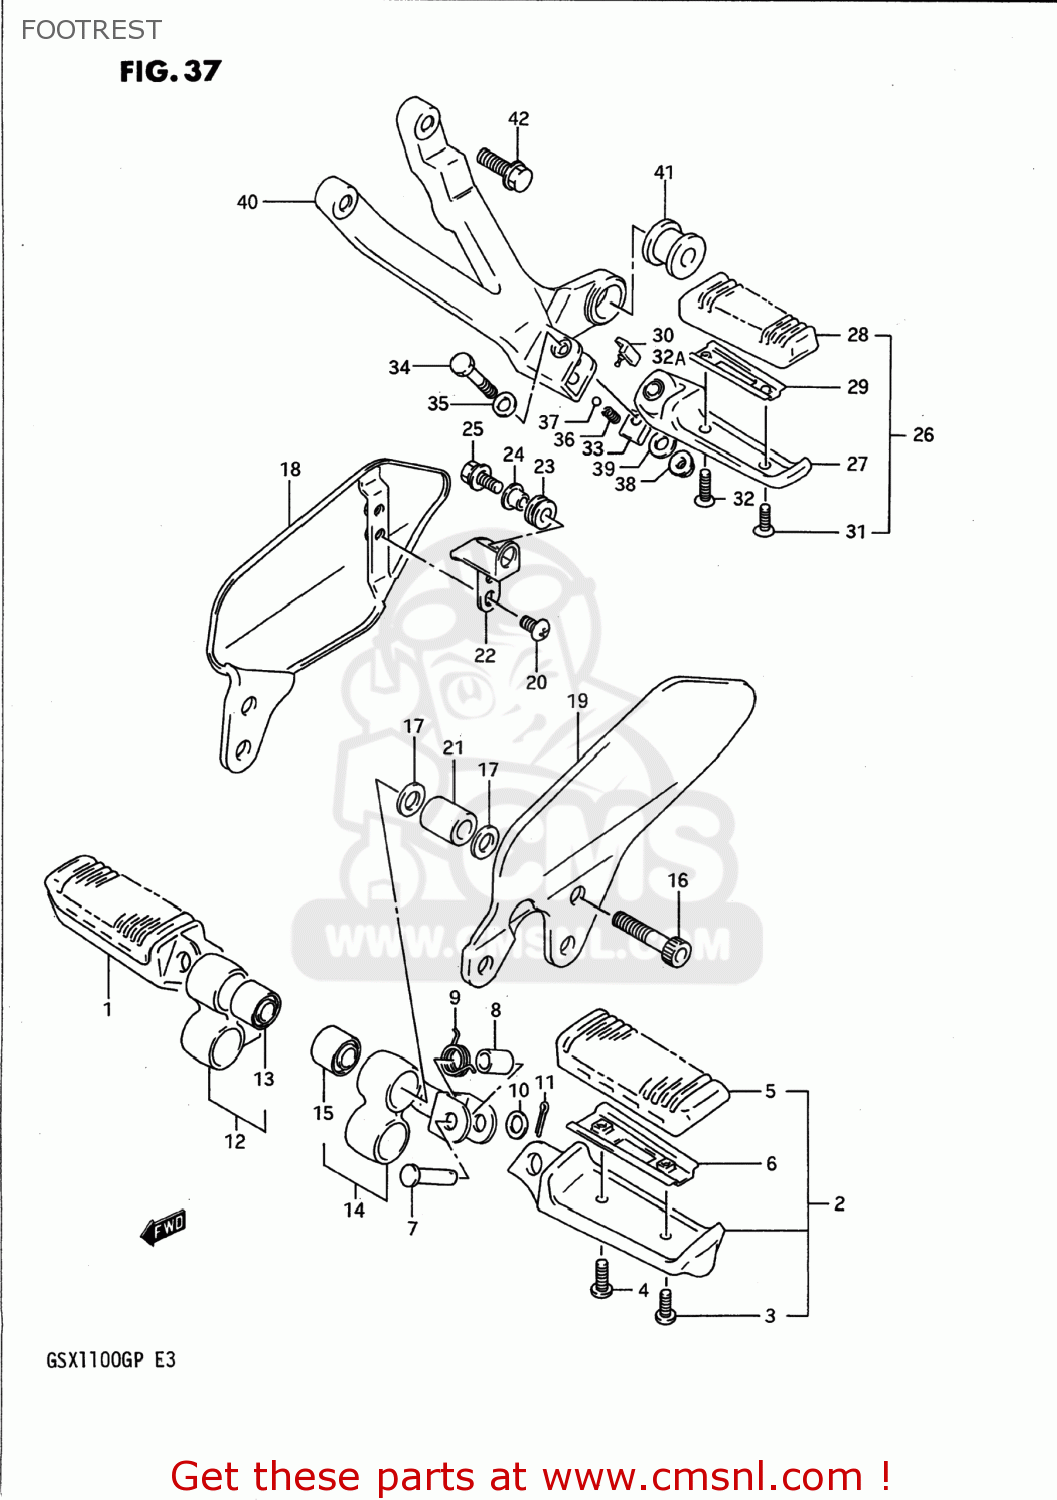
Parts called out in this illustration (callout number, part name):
1	FOOTREST ASSY,FR,R
2	FOOTREST ASSY,FR,L
3	SCREW
4	SCREW
5	RUBBER,FOOTREST
6	PLATE,FR FOOTREST RUBBER
7	PIN
8	SPACER(8.1X12X22)
9	SPRING
10	WASHER
11	PIN 20X20
12	HOLDER,FRONT FOOTREST
13	BUSH
14	HOLDER COMP,FRONT FOOT
15	BUSH
16	BOLT
17	WASHER
18	GUARD,FRONT FOOTREST,RIGHT
19	FOOT GUARD,LH
20	SCREW(6X8)
21	SPACER,FRONT FOOTREST
22	PLATE,FRONT FOOTREST GUARD
23	CUSHION
24	WASHER
25	BOLT
26	FOOTREST ASSEMBLY,PILLION
27	BAR COMP,PILLION FOOTREST
28	RUBBER,RR FOOTREST
29	PLATE,RUBBER STOPPER
30	CUSHION,PILLION FOOTREST
31	SCREW 5X12
32	SCREW 5X16
32A	CUSHION,PILLION FOOTREST
33	PLATE,SPRING STOP,R
34	BOLT(6X45)
35	SHIM(8.2X22X0.2)
36	SPRING
37	BALL
38	NUT
39	WASHER
40	BRACKET,PILLION FOOTREST
41	BUSH(10.2X25X19)
42	BOLT
